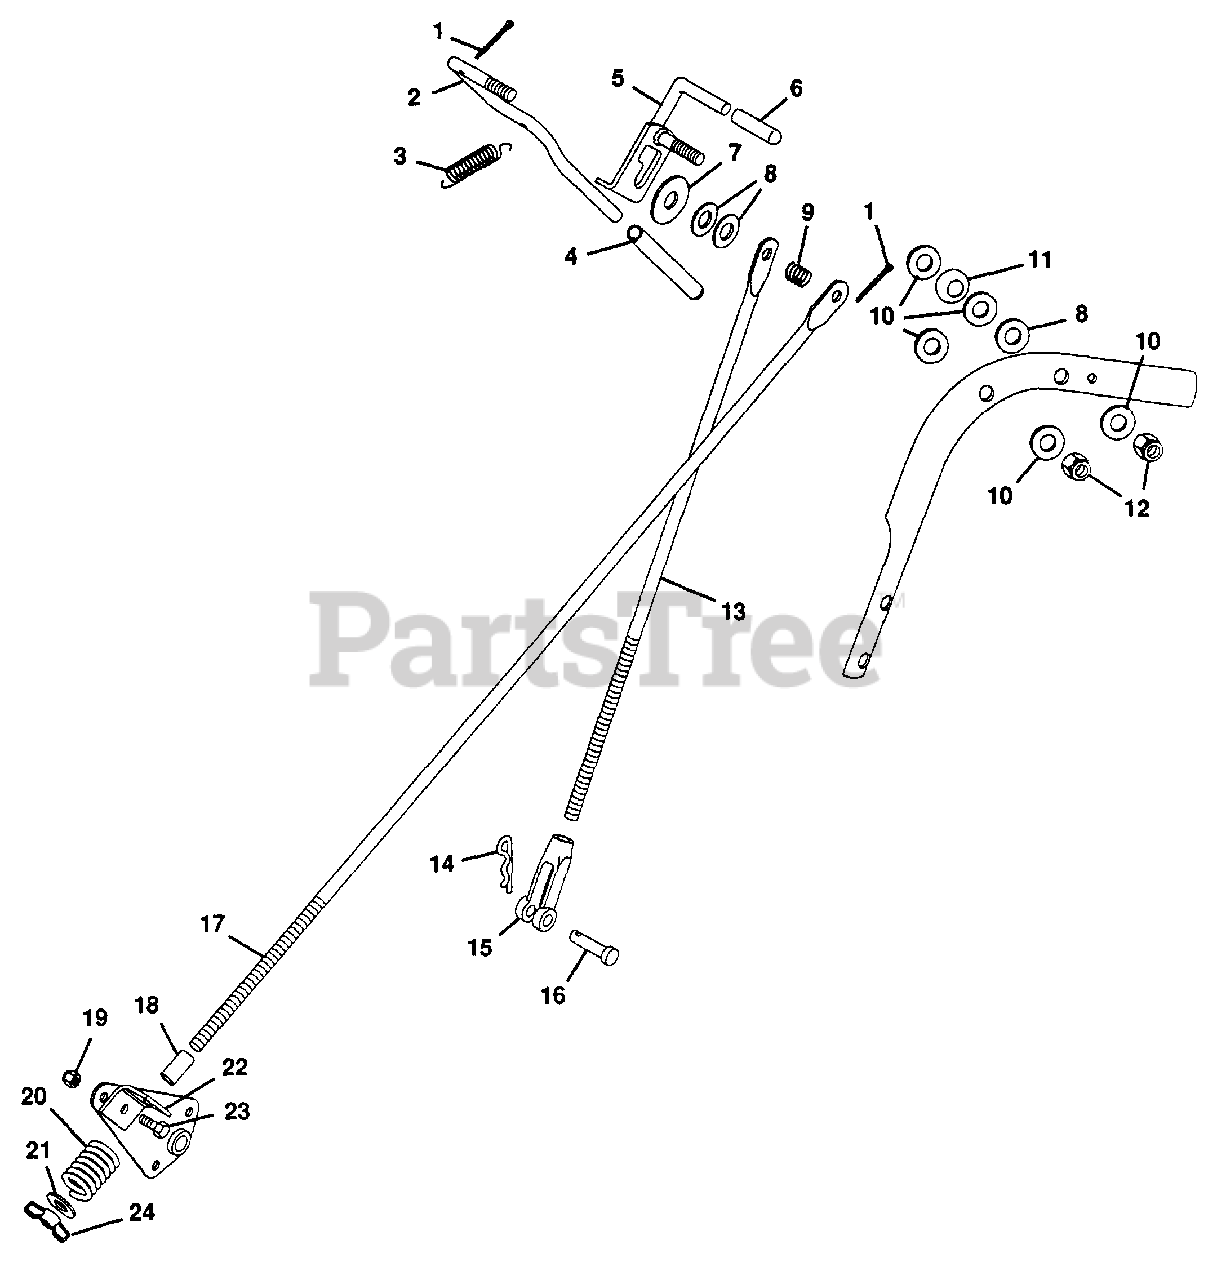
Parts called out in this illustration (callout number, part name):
1	PIN, COTTER .09X.75
2	LEVER, HAND CLUTCH
3	SPRING, EXTENSION
4	GRIP, HAND CLUTCH LEVER
5	WELDMENT, CLUTCH BRAKE
6	TIP, BRAKE LOCK LEVER
7	WASHER, FLAT .438X1.375X.083
8	WASHER, FLAT .406X.812X.065
9	SPRING, COMPRESSION
10	WASHER, NYLON .375X.75X.06
11	WASHER, SPRING .375 I.D.
12	NUT, LOCK 3/8-16
13	ROD, CLUTCH ACTUATING
14	PIN, COTTER HAIR
15	CLEVIS, 5/16-24 ADJUSTABLE
16	PIN, CLEVIS .312X.812
17	ROD, BRAKE
18	BUSHING, ST. .327X.411X.2.0 STL.
19	NUT, LOCK 1/4-20
20	SPRING, COMP. 1X.78X338
21	WASHER, FLAT .344X.688X.065
22	BRACKET, BRAKE ROD
23	BOLT, HEX 1/4-20X.625
24	NUT, WING 5/16-18
